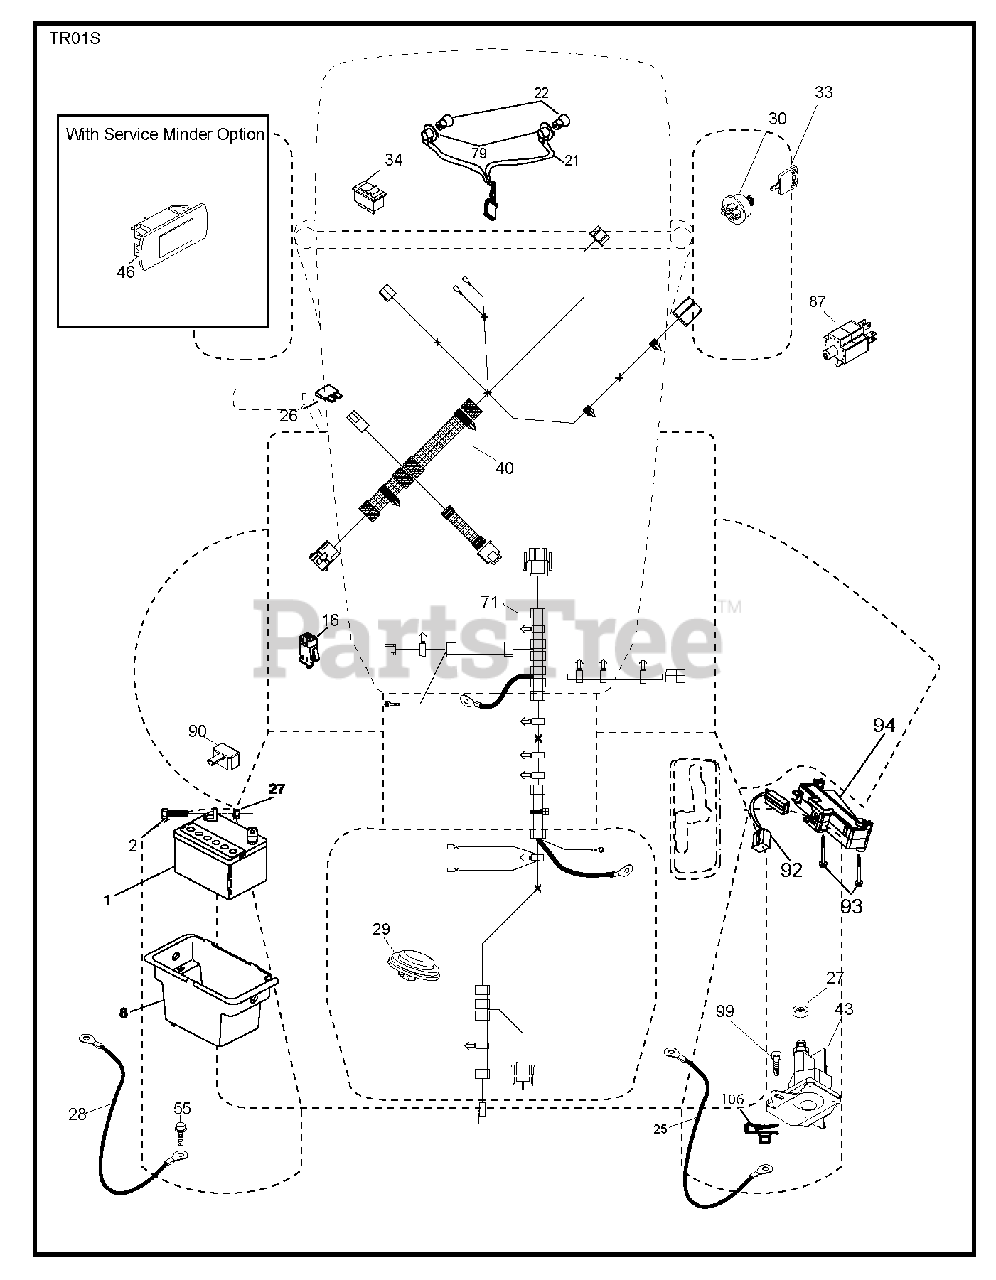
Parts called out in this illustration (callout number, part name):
1	REPL BY 532 12 38-99
8	BOX.BATTERY.MNT.REAR.L
16	SWITCH INTERLOOK PUSH-IN
21	HARNESS.LIGHT W/4152J BULBS
22	LIGHTBULB
25	Positive Battery Cable, Red 8 Ga 17
26	FUSE 20AMP
27	NUT
29	SWITCH.SEAT.DELTA.OPC.
30	SWITCH.IGN.DELTA.W.LGH.ROS
33	KEY.CHAIN.BLISTER.PACK.GEN.INT
34	SWITCH LT
40	Dash Harness, Tex Rear Batt
43	SOLENOID.W/BRASS.PLUNG
55	SCREW 5/16"
71	Harness, Tex Chssis.Rear.Batt
79	BULB HOLDER ASM.
87	SWITCH.INTRLCK.CLUTCH.
90	COVER.TERMINAL.BATTERY
92	HARNESS.PIGTAIL.CONSLE
93	SCREW.PLASTITE
94	MODULE.REVERSE.ROS
99	SCREW HEXWSHR 1/4-20X3/4
106	1/4-20 U NUT
